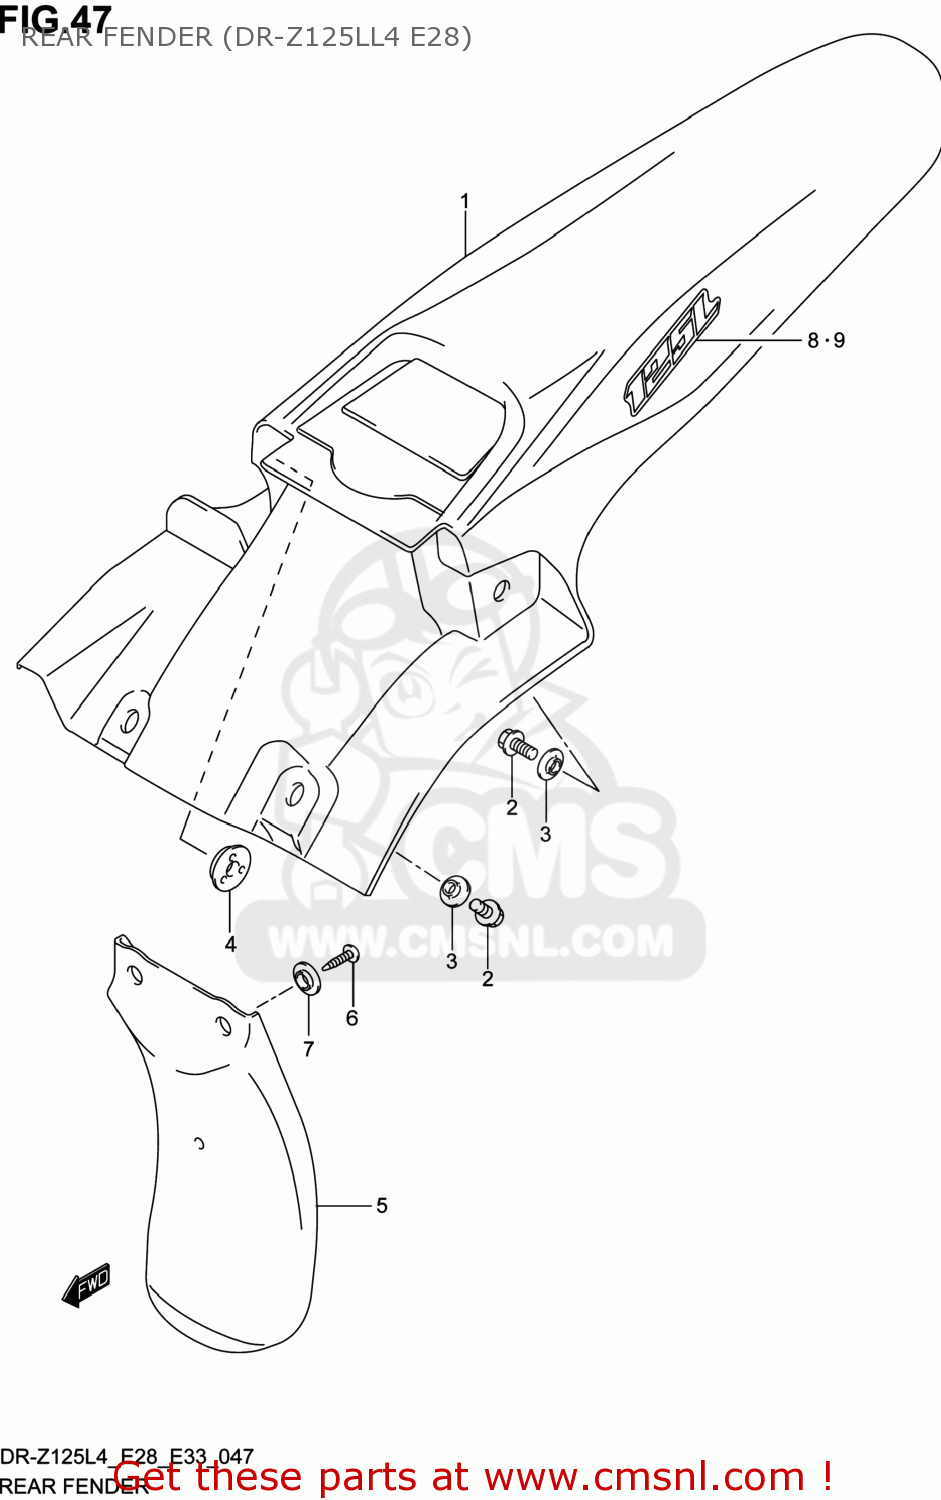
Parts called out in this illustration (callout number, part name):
1	FENDER,RR
2	BOLT(6X16)
3	WASHER
4	WASHER
5	MUDGUARD,RR FENDER FR
6	SCREW(5X16)
7	WASHER
8	EMBLEM,125L,R
9	EMBLEM,125L,L
